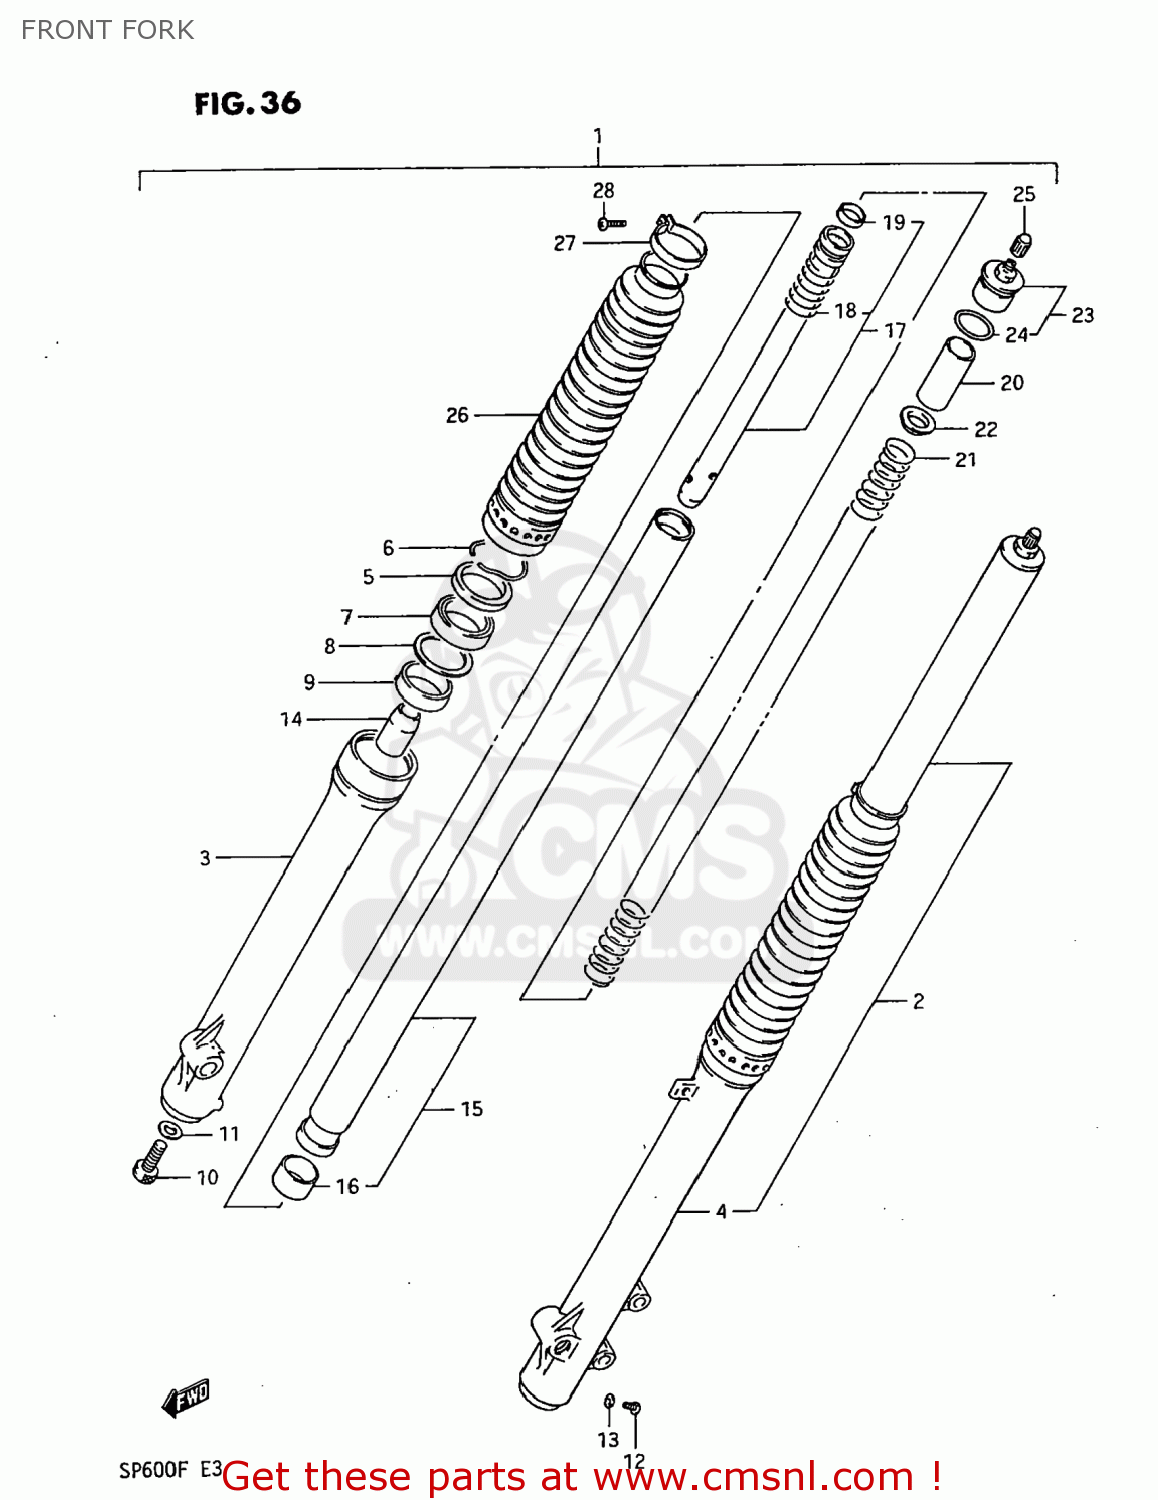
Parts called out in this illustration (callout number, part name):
1	DAMPER ASSEMBLY,FRONT FORK,RIGHT
2	DAMPER ASSEMBLY,FRONT FORK,LEFT
3	TUBE,FORK,OUTER,RIGHT
4	TUBE,FORK,LEFT,OUTER
5	SEAL,DUST
6	RING,OIL SEAL STOPPER
7	SEAL,OIL
8	WASHER,FORK OIL SEAL
9	METAL,FR FORK SLIDE
10	BOLT,CYLINDER
11	GASKET,CYLINDER (NAS)
12	SCREW 4X6
13	GASKET,DRAIN,PLUG (NAS)
14	PIECE,FRONT FORK OIL LOCK
15	TUBE,FORK,INNER
16	METAL,SLIDE FR FORK
17	CYLINDER,FRONT FORK
18	SPRING,REBOUND
19	RING,FRONT FORK PISTON
20	SPACER,FRONT FORK SPRING
21	SPRING,FRONT FORK
22	GUIDE,FR FORK SPRING
23	CAP,FORK INNER TUBE
24	O RING
25	CAP
26	BOOT
27	BAND,BOOT
28	SCREW 4X10
